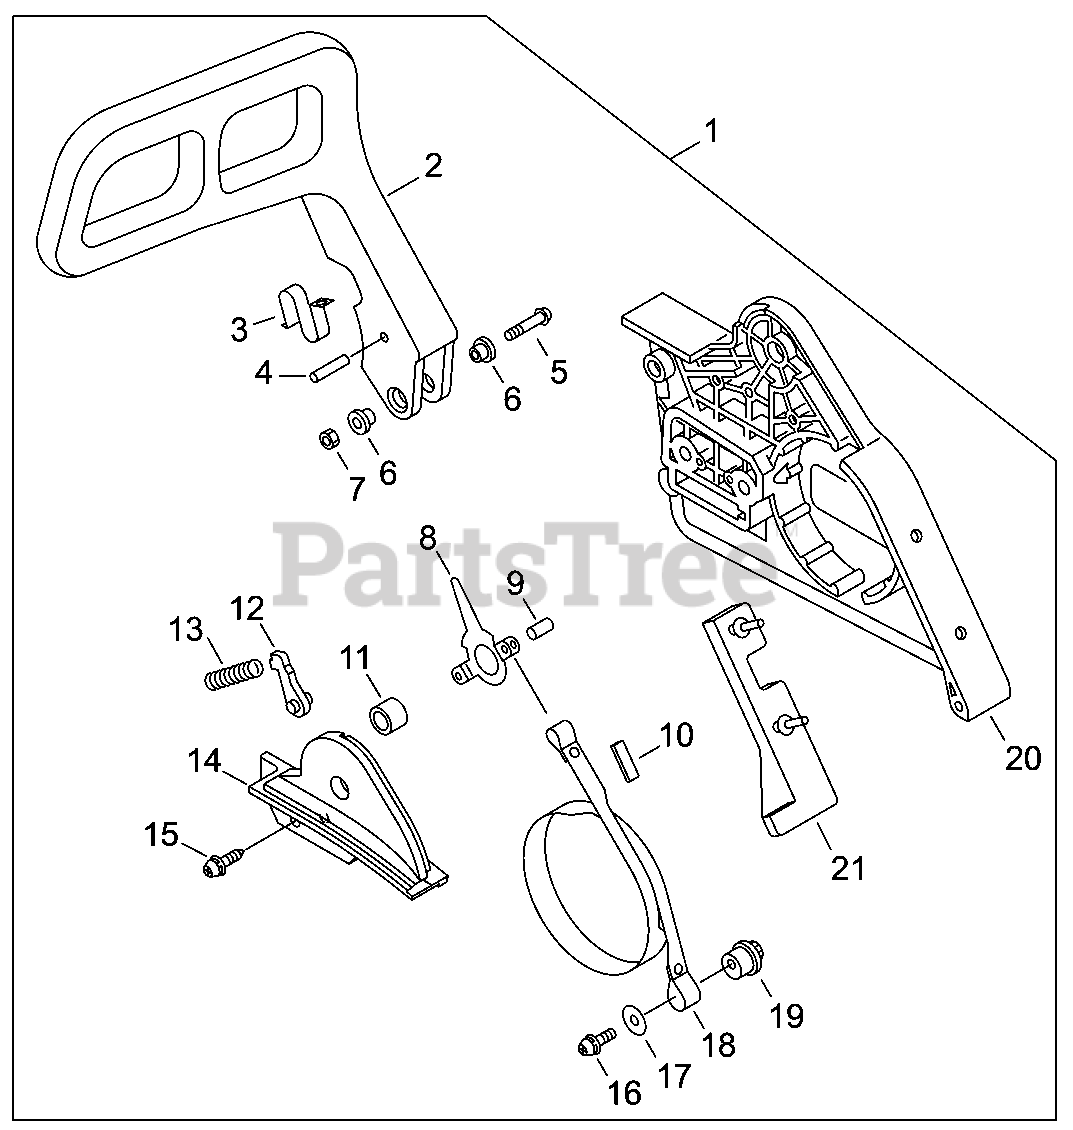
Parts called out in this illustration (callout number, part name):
1	BRAKE ASSY, CHAIN
2	LEVER, BRAKE
3	SPRING, FLAT
4	PIN 3.5×26
6	COLLAR 5.3×10×13×L5
7	NUT, FLANGE M5
8	LEVER, BRAKE
9	PIN, SPRING 4×8.8
10	SEAL, BRAKE
11	WASHER 5.2×12×14
12	STOPPER, BRAKE
13	SPRING, BRAKE
14	COVER, BRAKE
15	SCREW 4×10
16	SCREW 5×25
18	BAND, BRAKE
19	ADJUSTER, BRAKE
20	GUARD, SPROCKET
